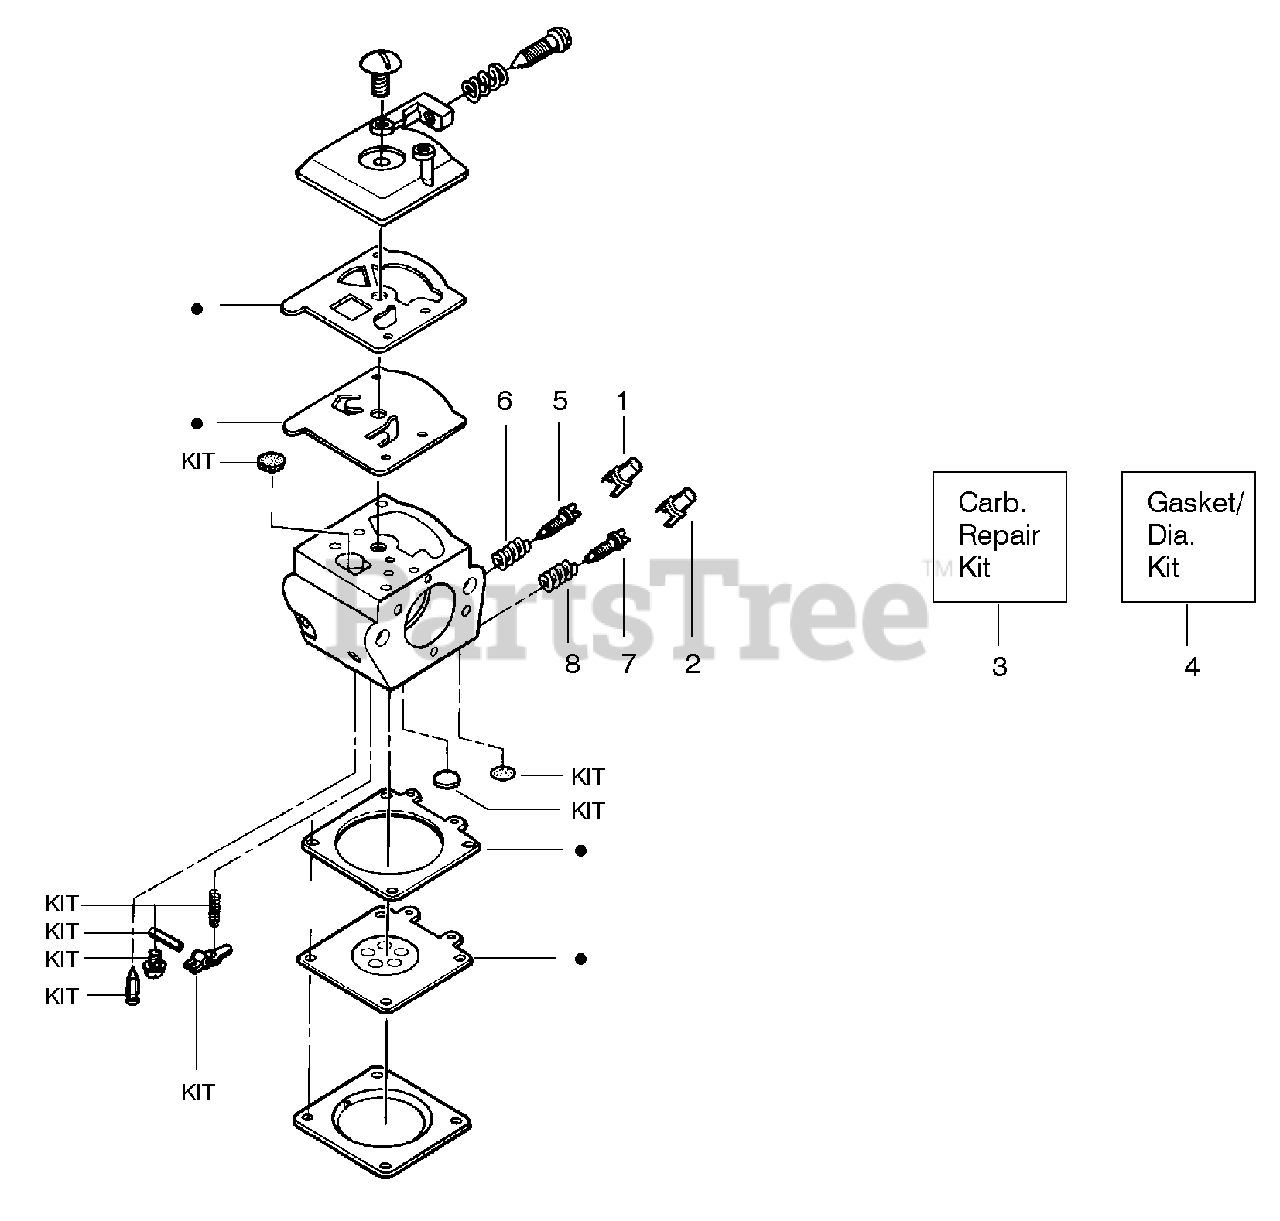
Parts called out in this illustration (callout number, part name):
1	Limiter Cap-High
2	Limiter Cap-Low
3	Carburetor Repair Kit
4	Gasket Diaphragm Kit
5	Needle-Low Speed
6	Needle Spring-Low Speed
7	Needle-High Speed
8	Needle Spring-High Speed
